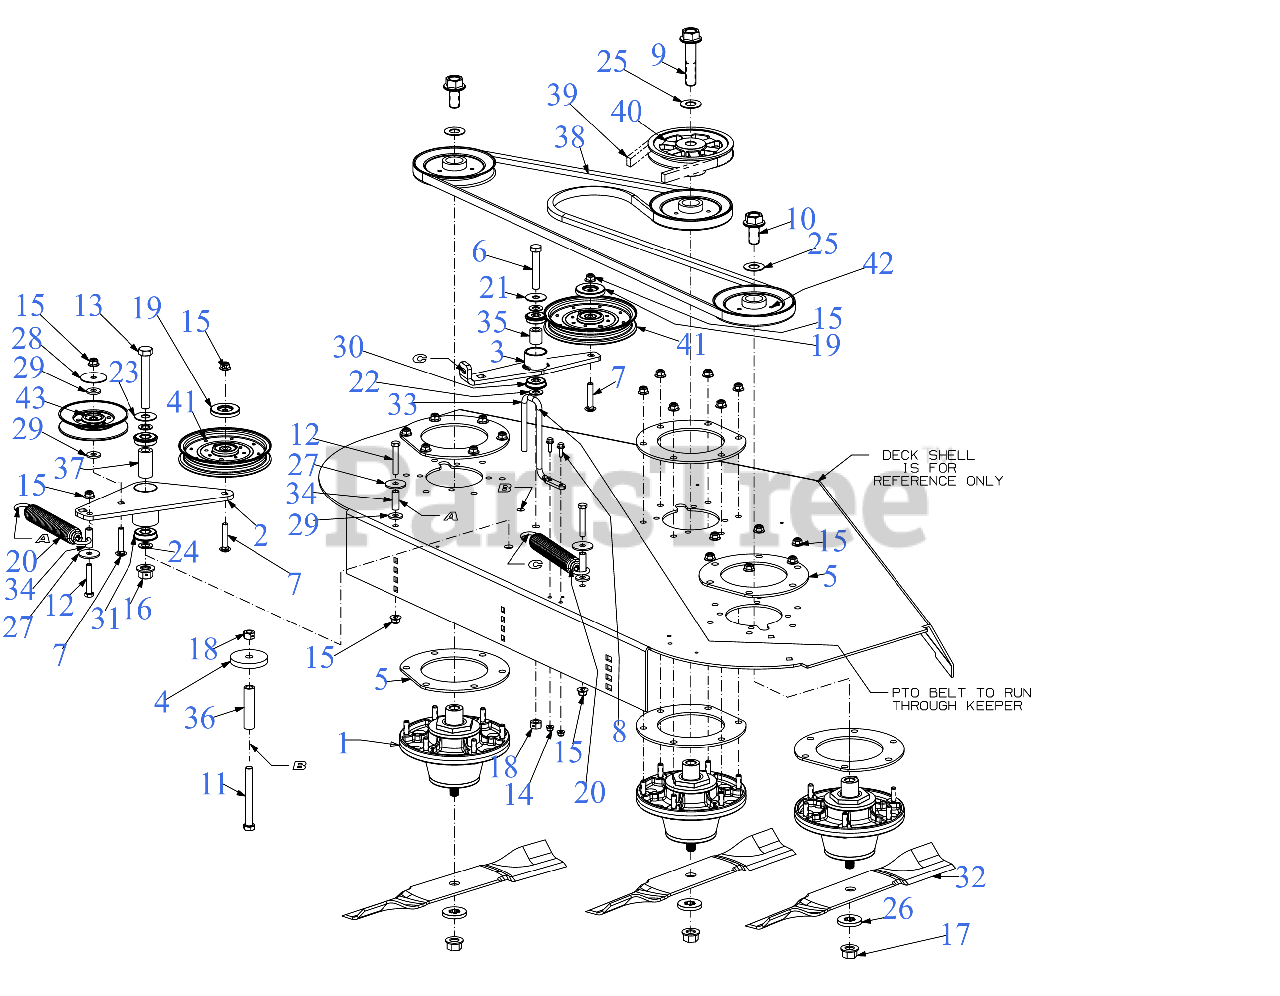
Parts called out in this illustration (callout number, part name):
1	SPINDLE ASSEMBLY
5	SPINDLE SUPPORT BRACKET TOP/BTM
6	SCREW-HEX 1/2-13 x 3.00
7	CARRIAGE BOLT 3/8-16 x 2
8	SCREW 1/4-20 x .75 GR5
9	CAP SCREW-HHFLG 3/4-10 X 3.50 GR8
10	CAP SCREW-HHFLG 3/4-10 X 1.50 GR8
11	SCREW 1/2-13 x 4.5 GR 5
12	SCREW 3/8-16 x 2.25 GR5
13	SCREW 5/8-18 x 4.25 GR5
14	FLANGE LOCK NUT
17	FLANGE NUT - 5/8-18 GDE 8
18	HEX NUT CTR LK 1/2-13
19	PULLEY CAP
20	SPRING 1.25" DIA x 8.5" LONG
21	FLAT WASHER
22	FLAT WASHER .510X.995
23	FLAT WASHER-.63IDX1.595ODX.62
24	FLAT WASHER
25	FLAT WASHER
26	FLAT WASHER - SPECIAL
27	FLAT WASHER .406X1.5X11
28	HUB CAP WASHER .406 x 1.92 x .060
29	FLAT WASHER .406ID X1.0 OD
30	ROLLER BEARING .5X1.37X.44
31	BALL BEARING W/RET
32	19" BLADE (HI LIFT)
32	Cub Cadet 54" HI LIFT BLADE SET
32	LOW-LIFT 19"BLADE (54"DECK)
32	BLADE- HI LIFT 19.0 XTREME
32	BLADE-19"MULCH 54"
32	19" XTREME BLADE
35	SPACER 0.51 x 0.88 x 1.00
37	SPACER 0.63 x 1.00 x 2.01
38	BELT-B SECTION 119.45"
39	V-BELT B SEC x 101.1
40	PULLEY-6.96 OD x .750 ID
41	IDLER PULLEY
42	SPINDLE PULLEY 6"
43	IDLER PULLEY 5.06 OD
